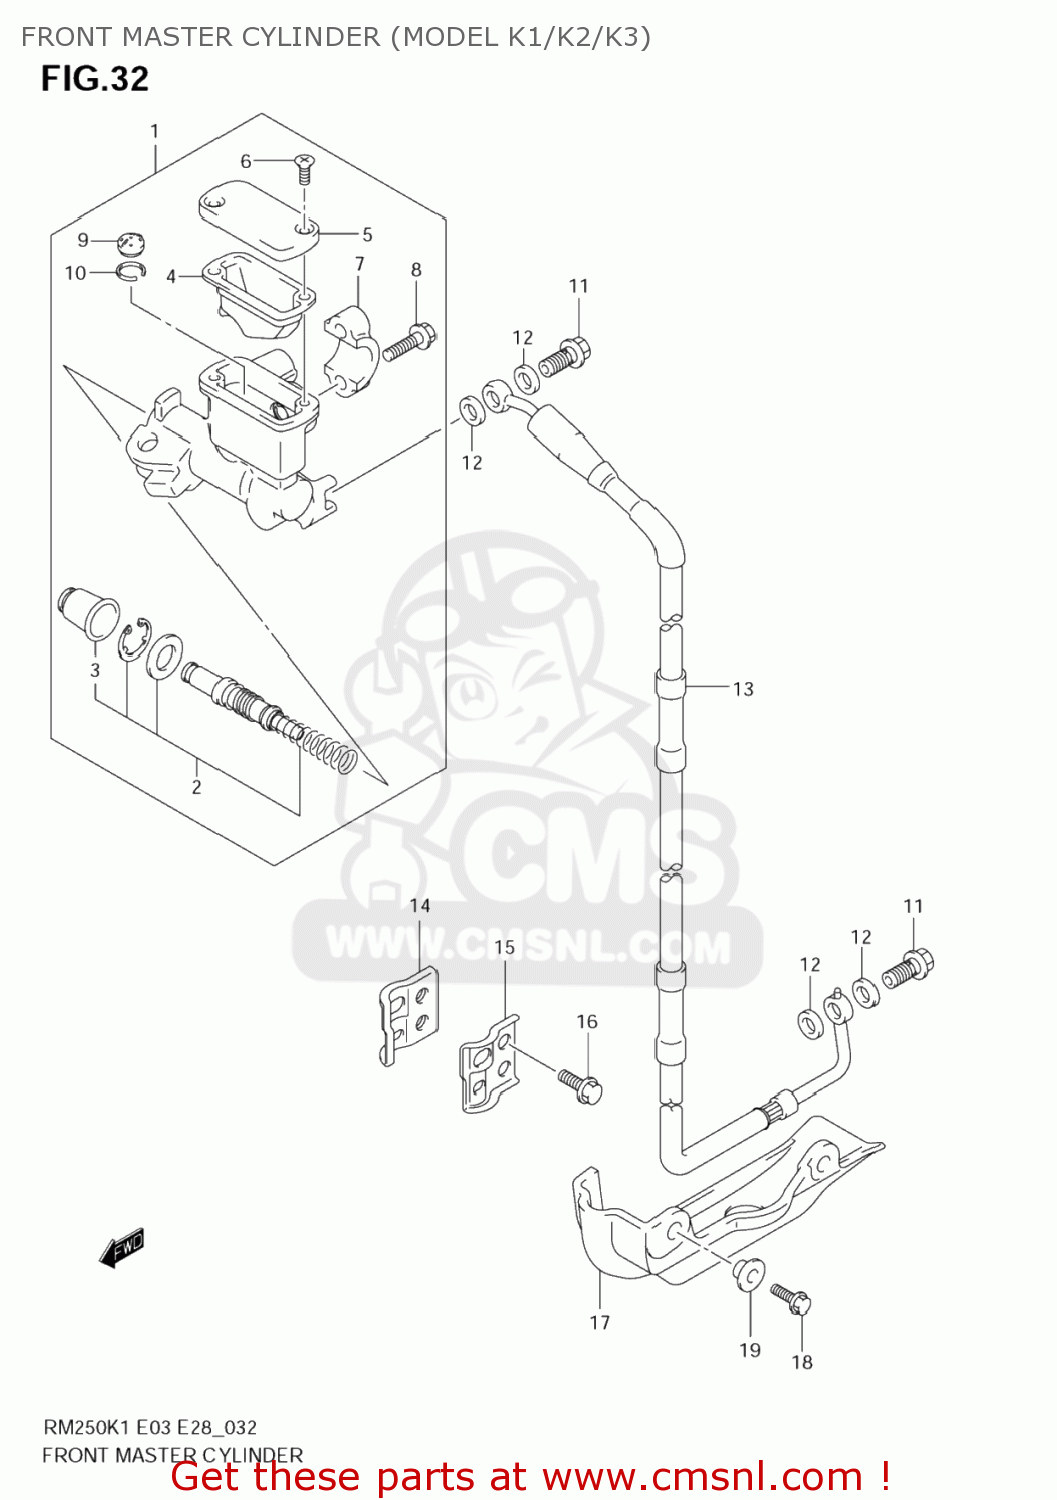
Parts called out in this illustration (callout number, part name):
1	CYLINDER ASSY,FR MASTER
2	PISTON & CUP SET
3	BOOT
4	DIAPHRAGM
5	CAP
6	SCREW
7	HOLDER
8	BOLT
9	SEPARATOR
10	RING
11	BOLT UNION
12	WASHER(10X15X1.5)
13	HOSE,FR BRAKE
14	CLAMP,FR BRAKE HOSE INNER
15	CLAMP,FR BRAKE HOSE OUTER
16	BOLT(6X16)
17	COVER,FR BRAKE HOSE
18	BOLT(6X12)
19	WASHER
